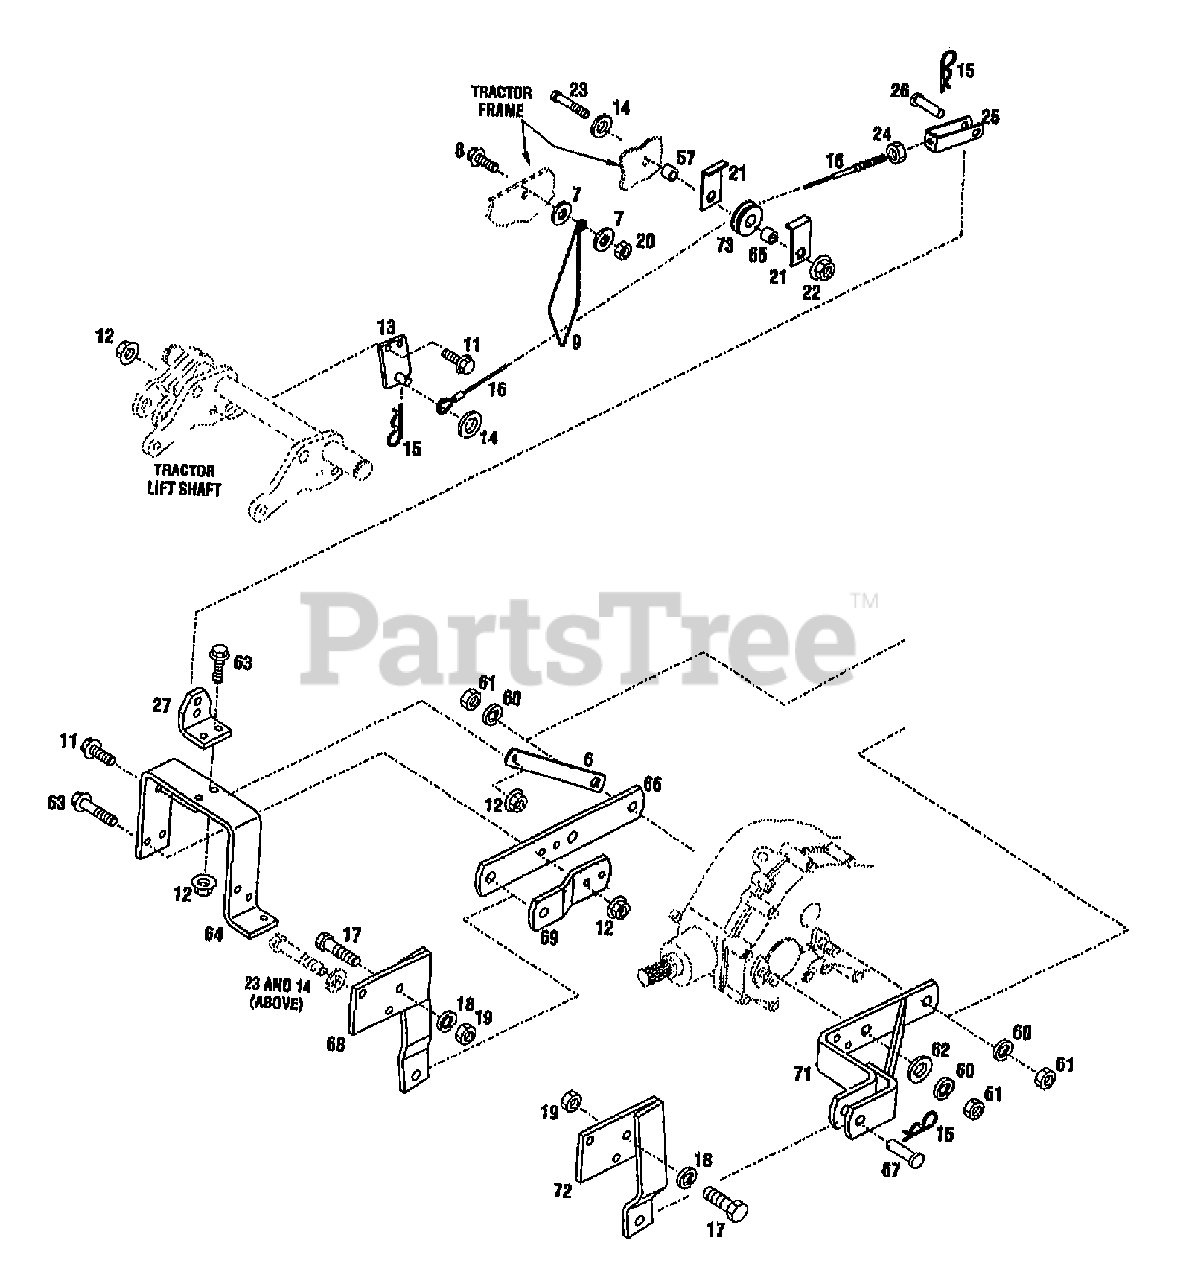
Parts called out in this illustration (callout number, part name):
6	BRACE-LIFT
7	WASHER-.875X.390X.134
8	SCR-HFLK 3/8-16X1.25 ZP
9	GUIDE-CABLE
11	SCR-HFLK 3/8-16X1.00 ZP
12	NUT-HFLK 3/8-16 ZP
14	WASHER-1.06X.531X.1 ZP
15	PIN-HITCH .125X2.56 ZP
16	CABLE-LIFT
17	SCR-HH 1/2-13X1.25 G5 ZP
18	WASHER-LK .5
19	NUT-HEX JAM 1/2-13
20	NUT-H/LK 3/8-16
21	RETAINER-CABLE
22	NUT-TOP LOCK 1/2-13 ZP
23	SCR-HH 1/2-13X2.5 G5 ZP
24	NUT-HEX/JAM 3/8-16
25	YOKE-CABLE
26	PIN-CLEVIS .5X1.25
27	BRKT-CABLE ANCHOR
57	SPACER-.875X.531X.47
60	WASHER-LK 1.072X.634X.156
61	NUT-HEX
62	WASHER-FLAT
63	SCR-HFLK 3/8-16X1.75 G5ZP
65	SPACER-.75X.53X.656
66	BRKT-LIFT
67	PIN-CLEVIS
68	ASSM-ARM HITCH RH
69	PLATE-DOUBLER
71	ASSM-HITCH ARM
72	ARM-HITCH LH
